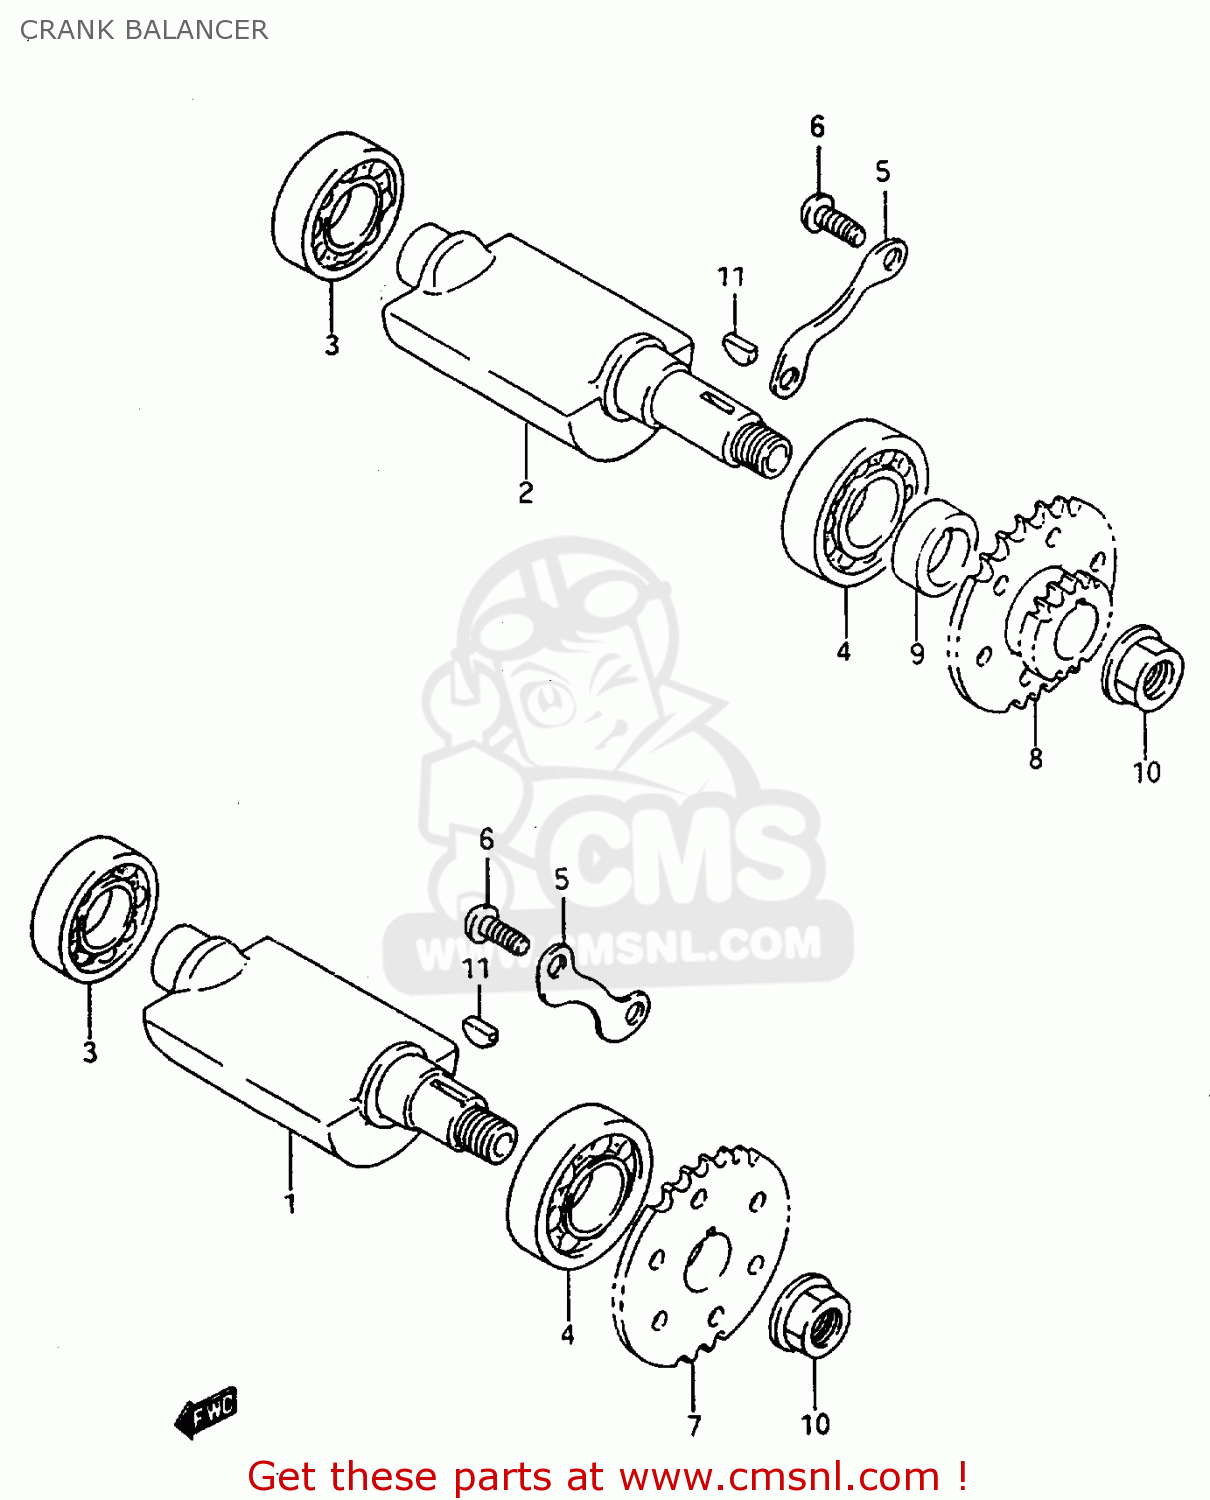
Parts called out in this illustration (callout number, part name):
1	BALANCER,CRANK FR
2	BALANCER, CRANK,REAR
3	BEARING(20X42X12)
4	BEARING(20X47X14)
5	RETAINER,CRANK BAL BEARING
6	SCREW
7	SPROCKET,BALANCER DRIVEN FR
8	SPROCKET,BAL.R
9	SPACER,CRANK BAL RR
10	NUT
11	KEY
